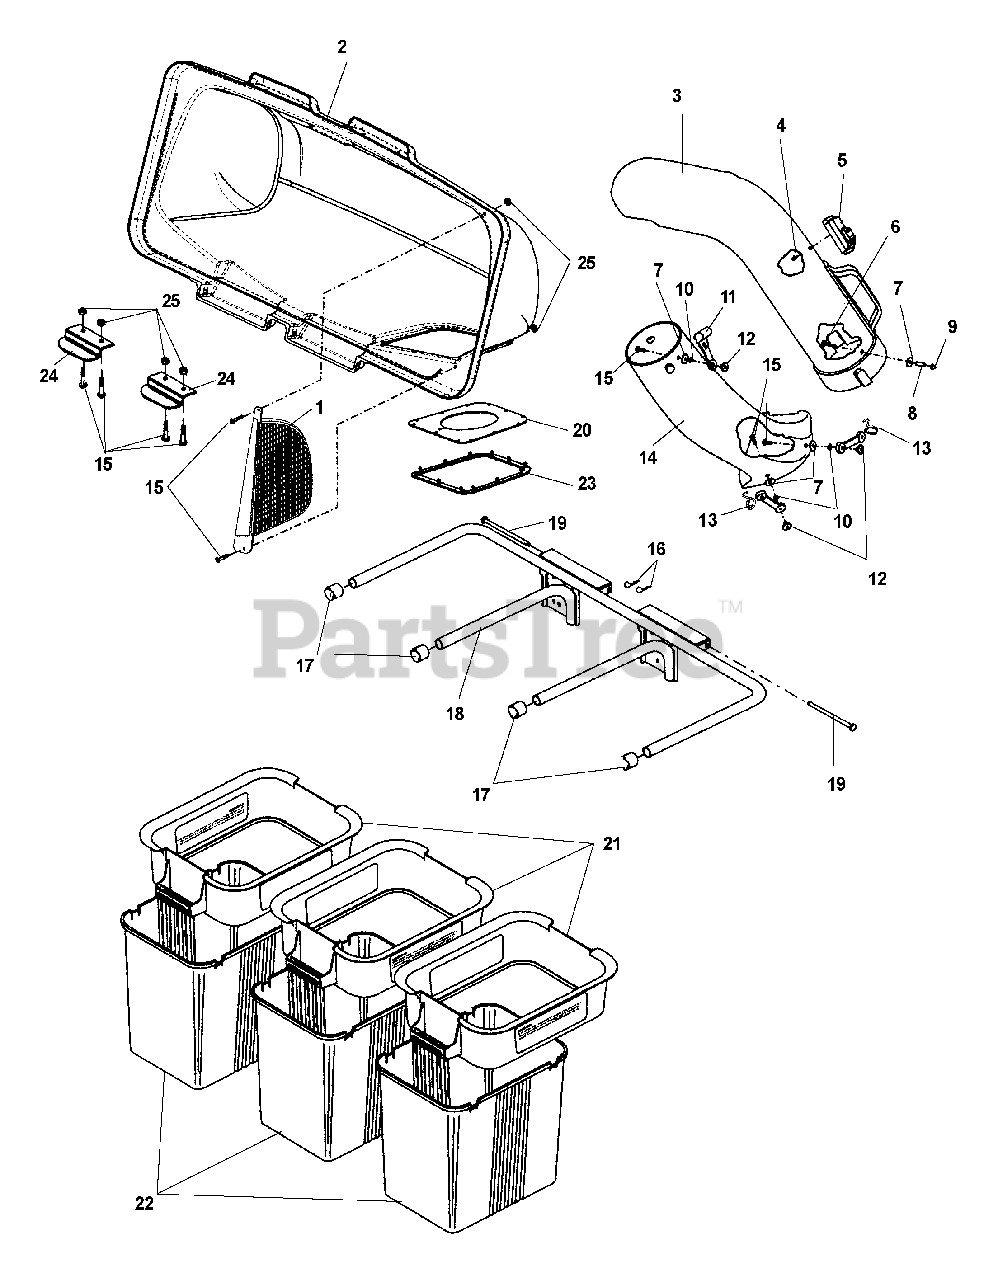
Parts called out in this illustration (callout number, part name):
1	Screen, cover
3	Chute, upper
4	Screw, #10-14 x 1/2, special
5	Dump bag indicator
6	Screw, #10-24 x 1 1/8
7	Washer, 3/16 x 3/4 x 16 Ga.
8	Spacer, split
9	Nut, #10-24, acorn
10	Lockwasher, 3/16
11	Latch, chute
12	Nut, weld
13	Latch, assembly
14	48" Chute, lower
14	54" Chute, lower
15	Screw, #10-24 x 5/8
16	Spring, retainer
17	Plug, tubing end
18	Bagger, frame
19	Pin, hinge
20	Gasket, cover
21	Container, top
22	Container, bottom
23	Seal, cover
24	Handle, bagger cover
25	Nut, #10-24, crownlock
